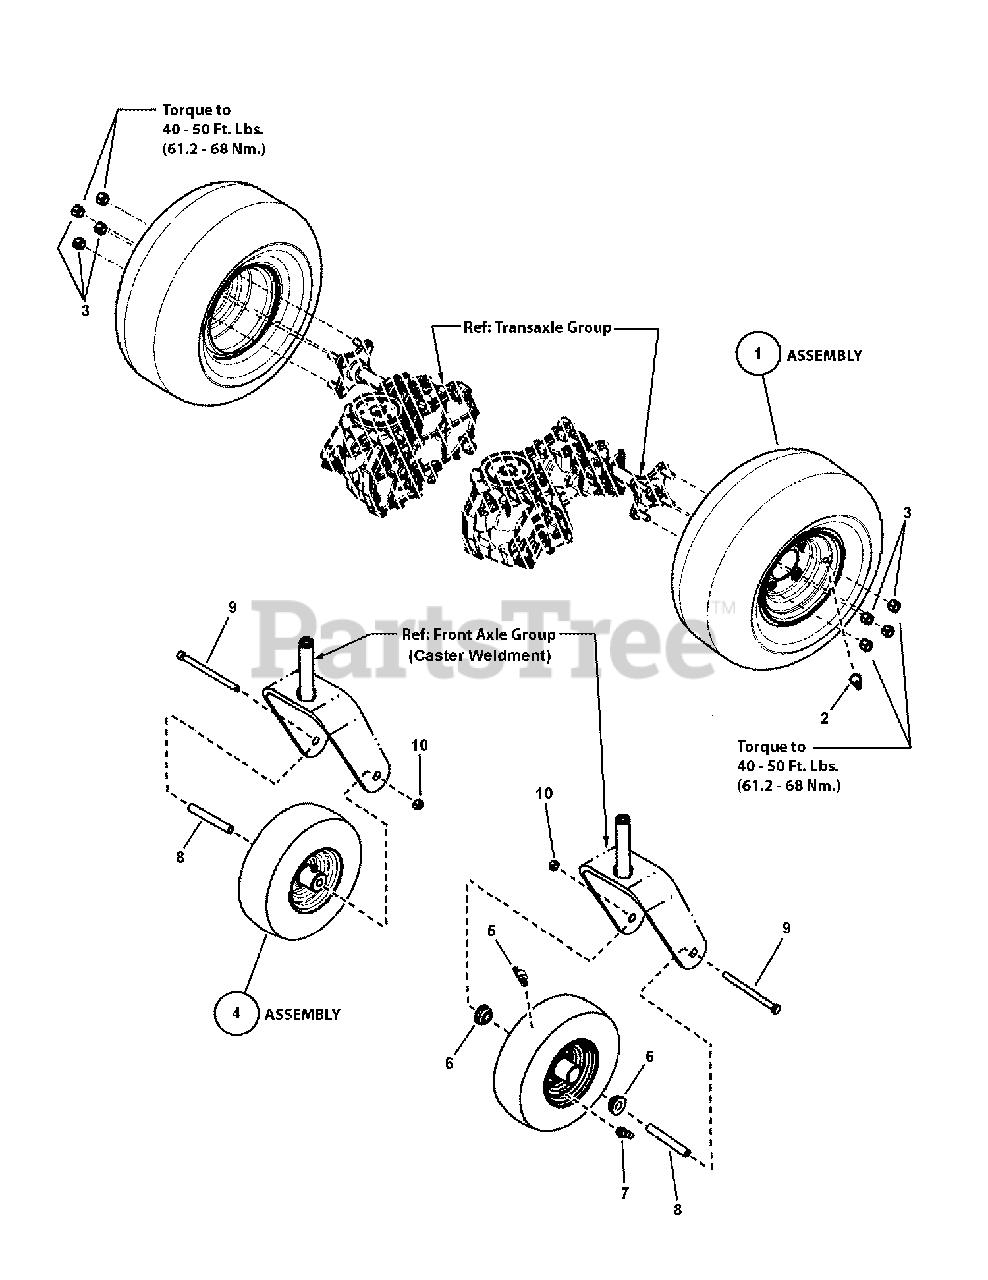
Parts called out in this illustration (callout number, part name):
1	ASSEMBLY, Rear Wheel, 20 x 10.0-8, 4P K500 PMS 877
1	ASSEMBLY, Rear Wheel, 18 x 9.50-8, K500, PMS 87
2	VALVE STEM & CAP, Air .453 Dia 0.88 Long
3	LUG NUT, 1/2-20, YZ
4	ASSEMBLY, 11 x 4.00-5, Front Wheel & Tire Caster
5	GREASE FITTING, (8M x 1 threads, 45 degree)
6	BUSHING, .632 ID, 1.377 OD, .62 LG, Front Wheel, PM
7	VALVE, Air
8	TUBE, Caster Wheel
9	SCREW, 7/16-14 x 6 Hex Head Cap, GR 5, YZ
10	NUT, 7/16-14 Hex Center Lock, GR 5, ZP
